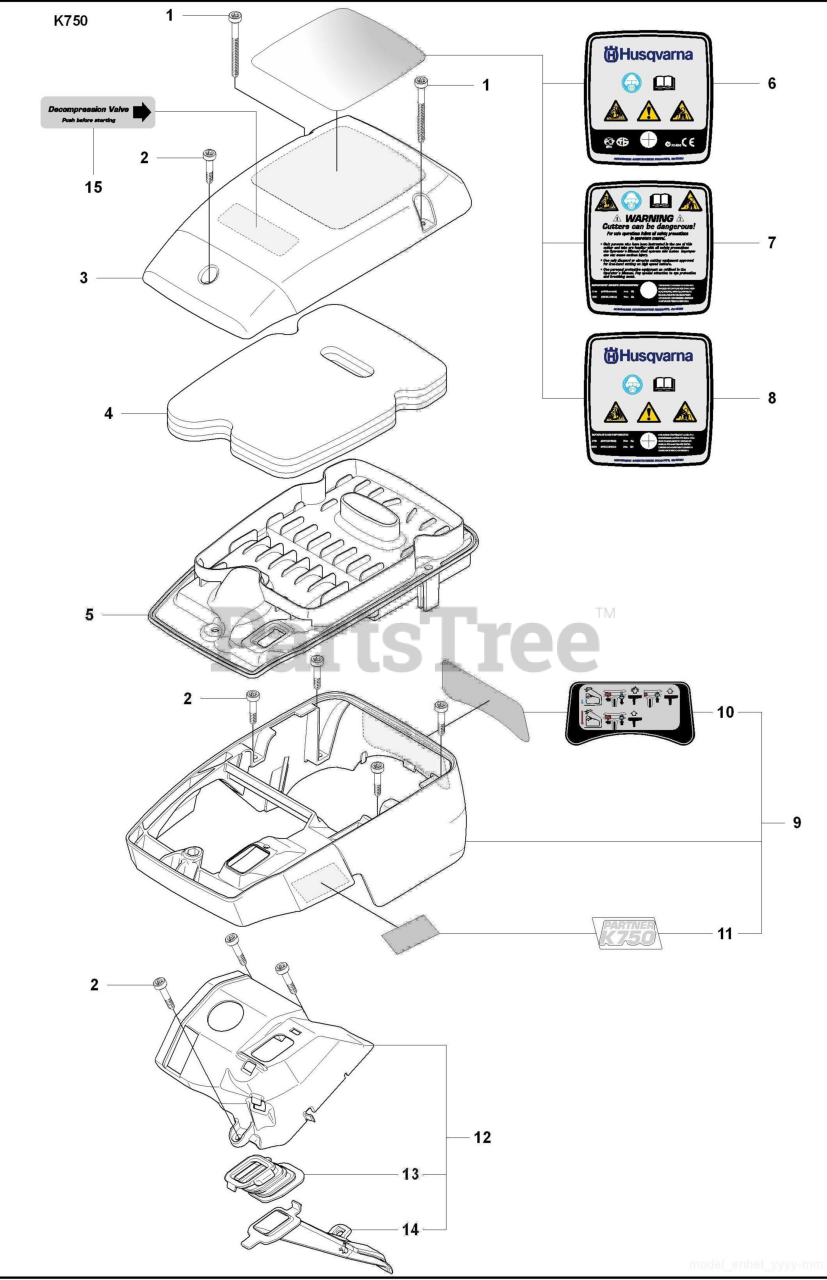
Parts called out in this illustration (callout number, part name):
3	FILTER COVER
5	FILTER BOTTOM
6	LABEL
7	LABEL
8	LABEL
9	CYLINDER COVER ASSY
11	LABEL
12	COVER
13	BELLOWS
14	AIR NOZZLE
15	Decal - Deko Valve
